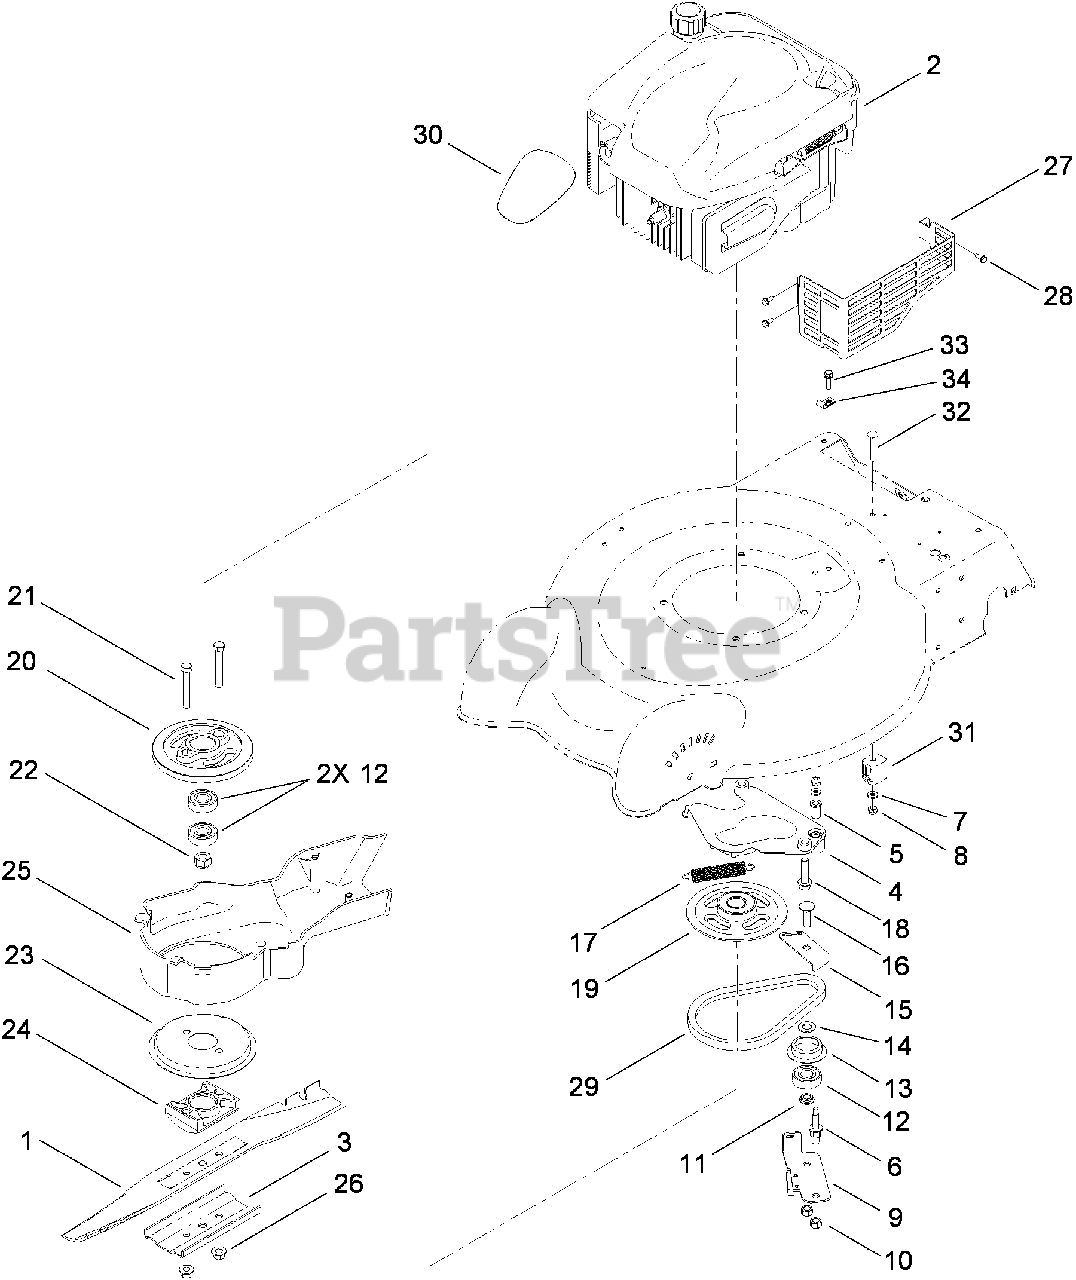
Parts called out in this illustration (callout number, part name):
1	BLADE-20 INCH
3	SUPPORT-BLADE
4	PLATE-ANCHOR
6	BOLT-SHOULDER
7	WASHER-FLAT
8	NUT-LOCK, NI
9	BRAKE ARM ASM
11	SPACER-BEARING
12	BEARING-BALL
13	RETAINER-BELT
15	PLATE-GUIDE
16	SCREW-CARR
17	SPRING-TENSION, BRAKE
18	SCREW-HWH
19	PULLEY-BBC
20	DRUM
21	SCREW-HH
23	DISC
24	SUPPORT-BLADE
25	COVER-BBC
26	NUT-LOCK
27	SHIELD-MUFFLER
28	SCREW-TAPTITE
30	DECAL-SHROUD
31	ANCHOR-CABLE, BBC
32	SCREW-CARR
33	SCREW-HWH
34	CLIP-CLOSED, INSULATED
